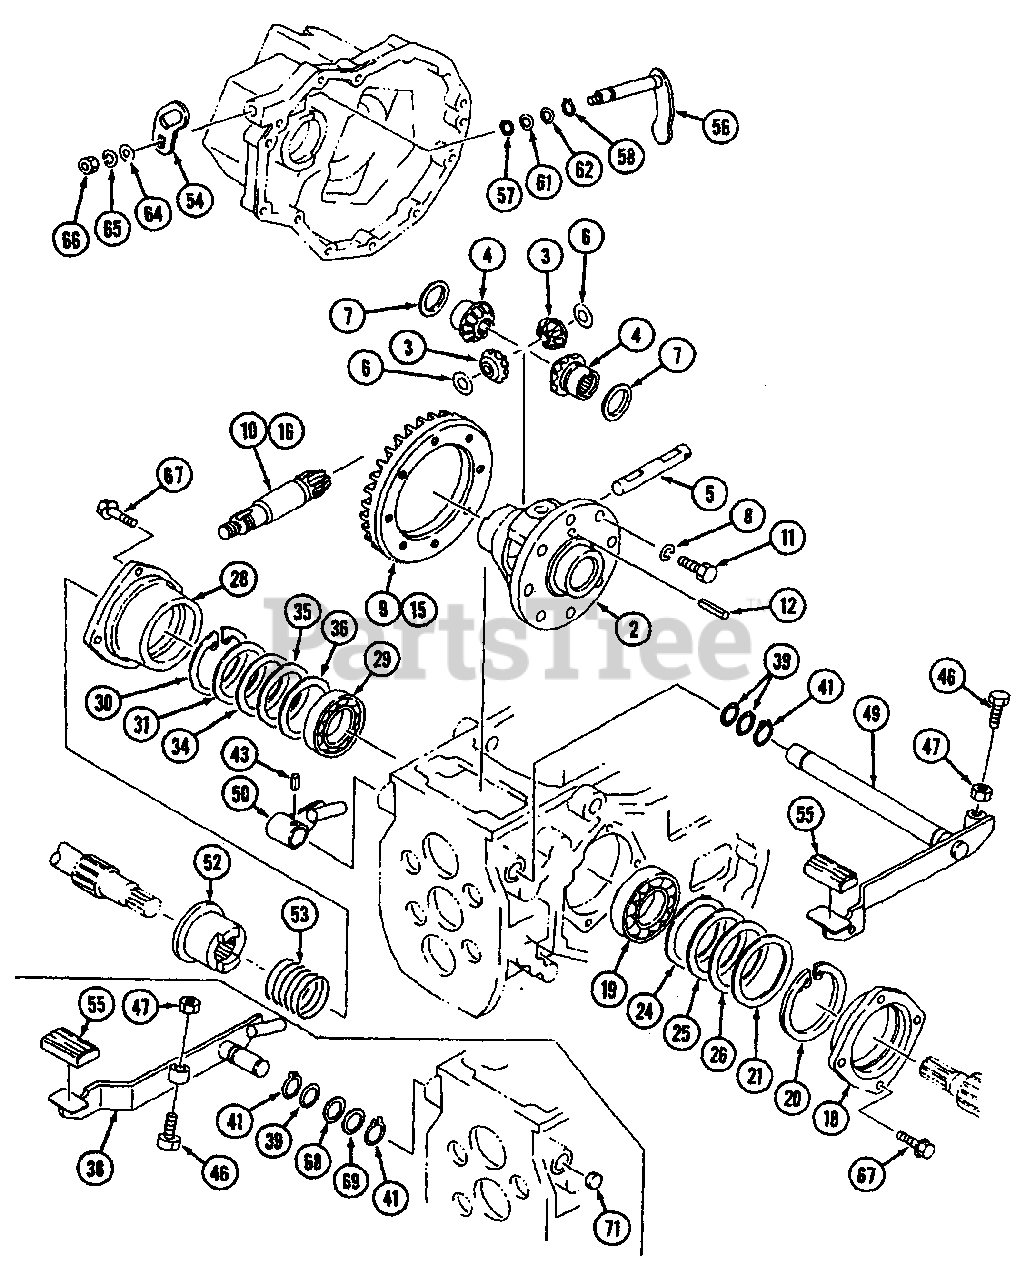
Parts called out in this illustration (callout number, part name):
2	Case Differential
5	Shaft, Pinion
6	Washer, Thrust
7	Washer, Thrust
9	Pinion & Ring Gear Set (2WD)
10	Pinion & Ring Gear Set (2WD)
11	Bolt, M8-1.25
38	Pedal Diff. Lock (Gear)
43	Pin, Spring (HST)
49	Pedal Diff. Lock (HST)
50	Arm, Diff. Lock (HST)
68	Liner t=0.4 (Gear)
69	Liner t=1.0 (Gear)
71	Seal, Cap (Gear)
